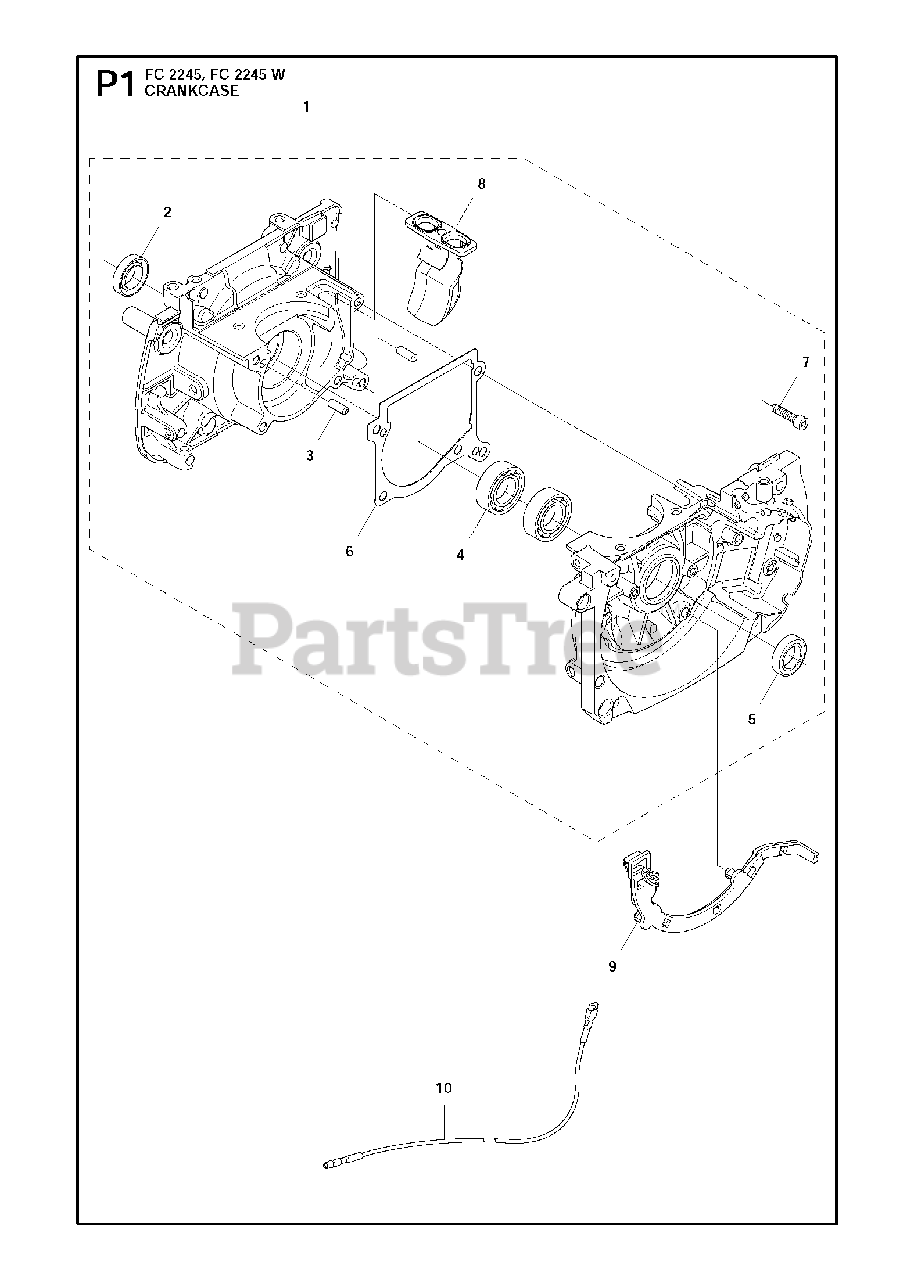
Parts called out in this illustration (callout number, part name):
1	CRANKCASE
2	RADIAL SEAL
3	PIN 5X14
4	BALL BEARING
5	SEAL RING
6	GASKET
7	SCREW MC6S 5X25
8	WALL
9	CABLE HOLDER
10	SHORT CIRCUIT CABLE
